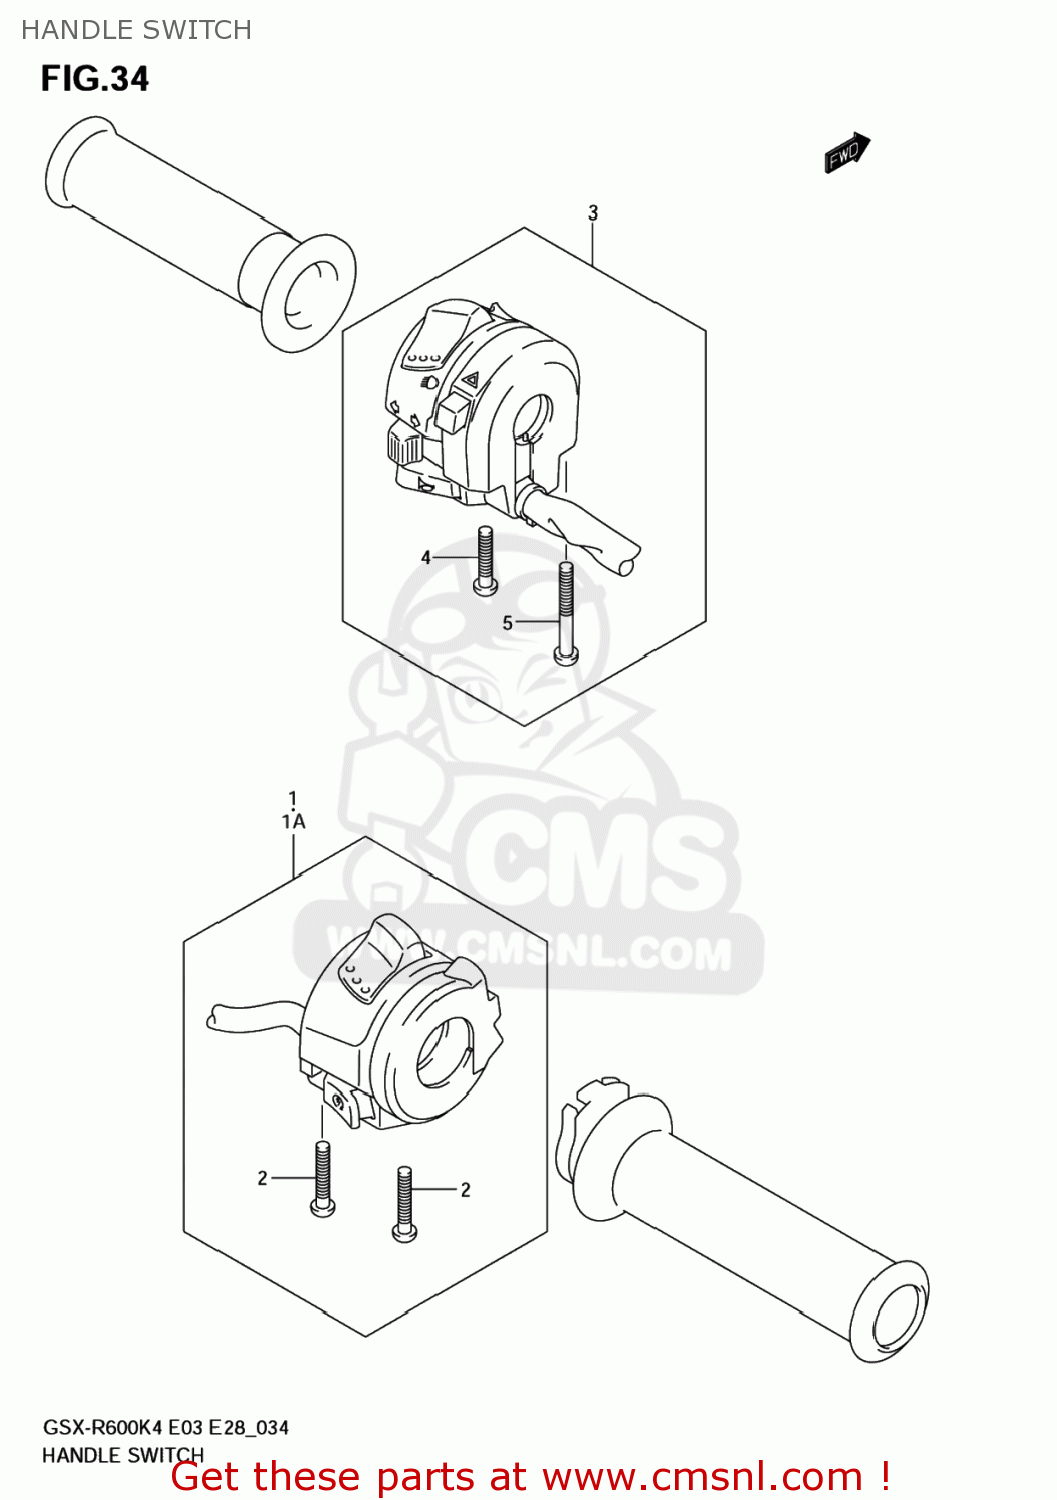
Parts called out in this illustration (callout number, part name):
1	SWITCH ASSY,HANDLE,R
1A	SWITCH ASSY,HANDLE,R
2	SCREW
3	SWITCH ASSY,HA
4	SCREW
5	SCREW
